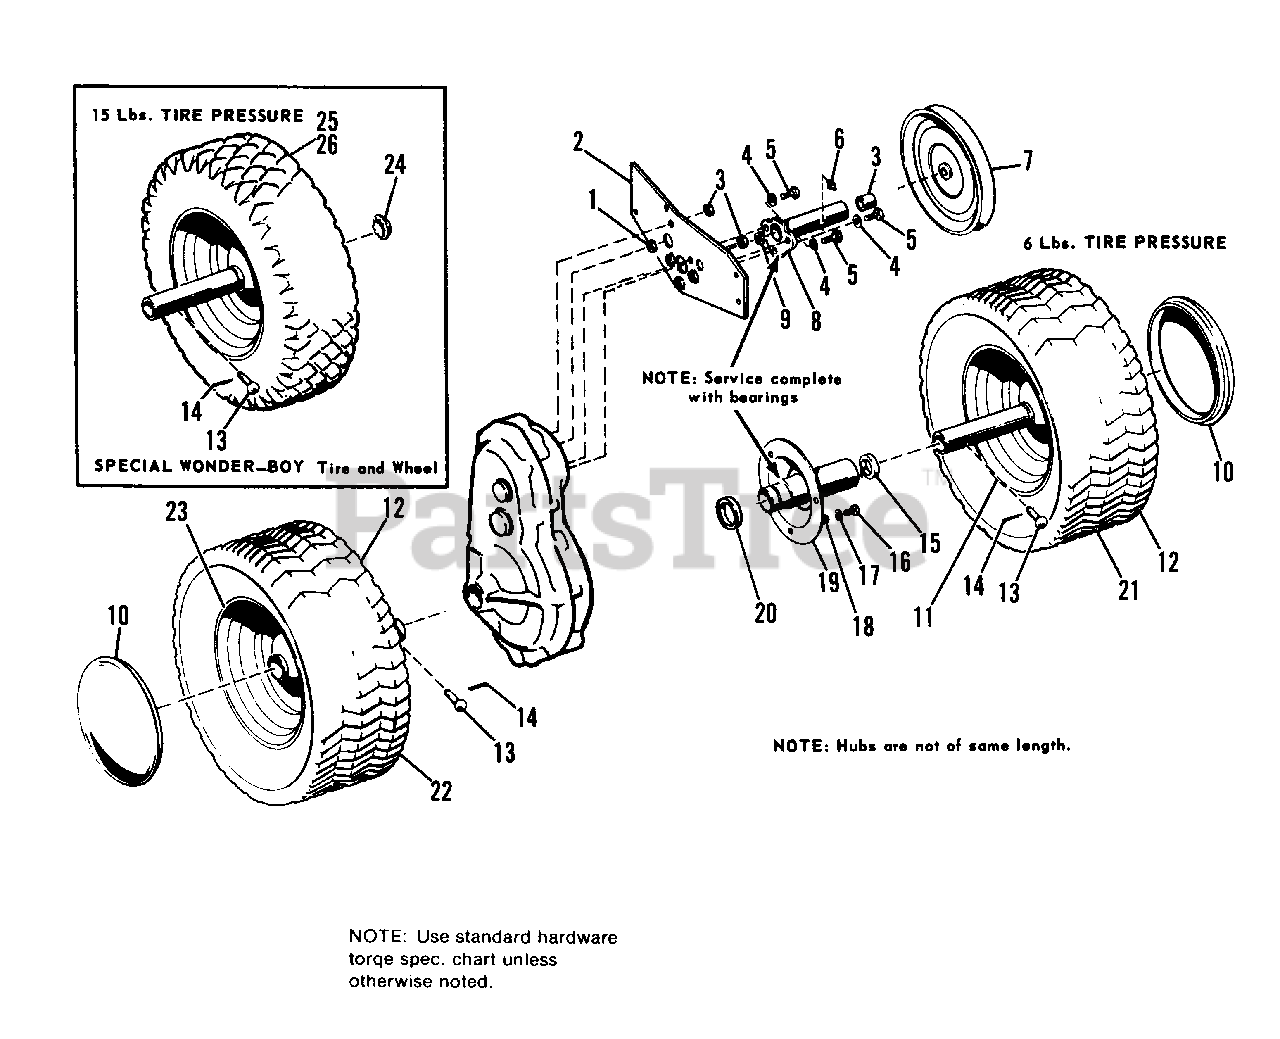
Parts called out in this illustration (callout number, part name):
1	NUT, Hex, Full, 7/16-14
2	PLATE ASSY., Side, L.H.
4	LOCKWASHER, 5/16
5	CAPSCREW, Hex Hd., 5/16-18 x 7/8
6	FITTING, Grease, #1641
7	PULLEY, Transmission
8	TUBE ASSY., W/Bearing
9	SEAL, Grease
11	WHEEL ASSY., R.H.
12	TIRE, Tubeless
13	PIN
14	PIN, Cotter, 1/8 x 3/4
16	CAPSCREW, Hex Hd., 3/8-16 x 7/8
17	LOCKWASHER, 3/8
18	WASHER, Plain, 3/8
19	HOUSING ASSY., Axle W/Bearings
21	WHEEL & TIRE ASSY., Rear, L.H.
22	WHEEL & TIRE ASSY., Rear, R.H.
23	WHEEL ASSY.,L.H.
24	BUTTON, Plug
25	WHEEL & TIRE ASSY., R.H.
26	WHEEL & TIRE ASSY., L.H.
